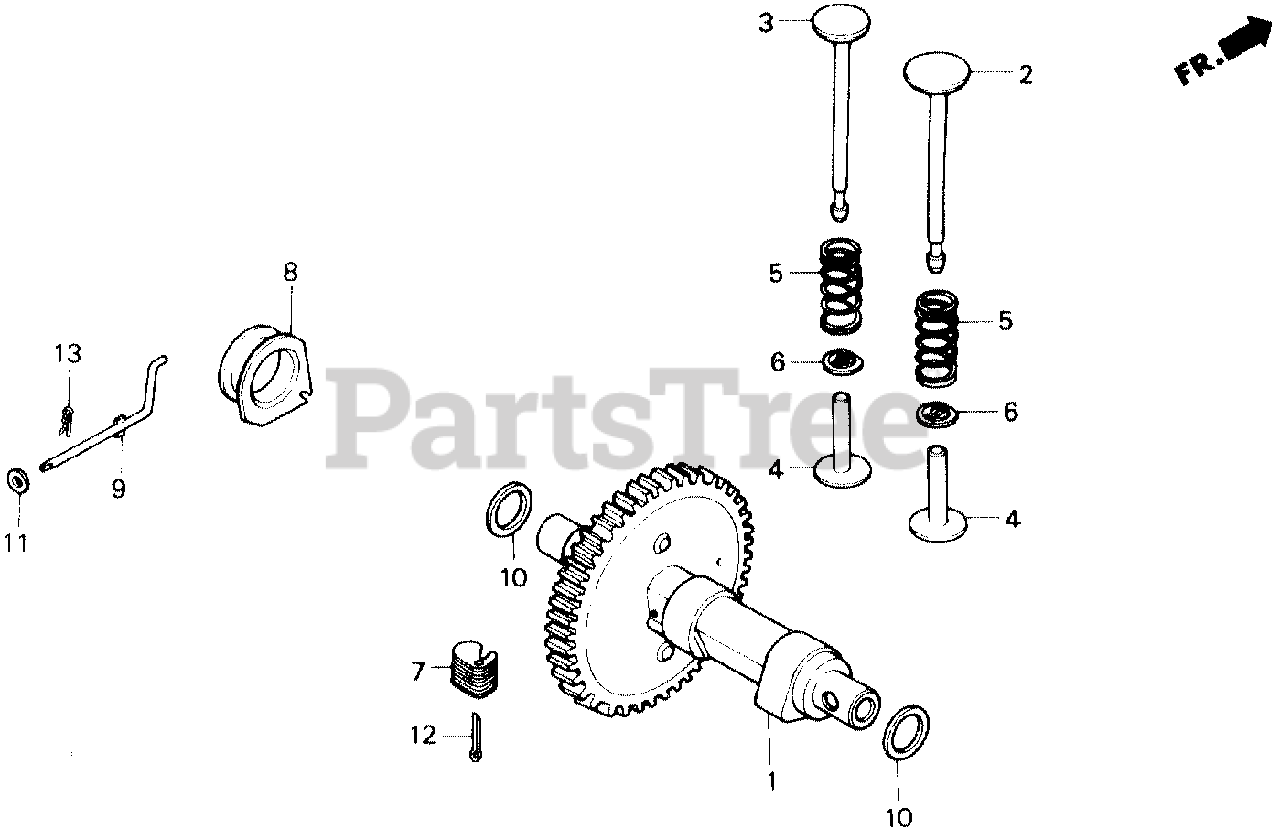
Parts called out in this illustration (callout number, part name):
1	CAMSHAFT ASSY.
2	VALVE, IN.
3	VALVE, EX.
4	LIFTER, VALVE (39.6MM)
4	LIFTER, VALVE (39.9MM)
5	SPRING, VALVE
6	RETAINER, VALVE SPRING
7	WEIGHT, GOVERNOR
8	SLIDER, GOVERNOR
9	SHAFT, GOVERNOR ARM
10	WASHER, THRUST (18MM)
11	WASHER, PLAIN (5MM)
12	PIN, SPLIT (3.0X25)
12	PIN, SPLIT (3.0X45)
13	PIN, LOCK (8MM)
